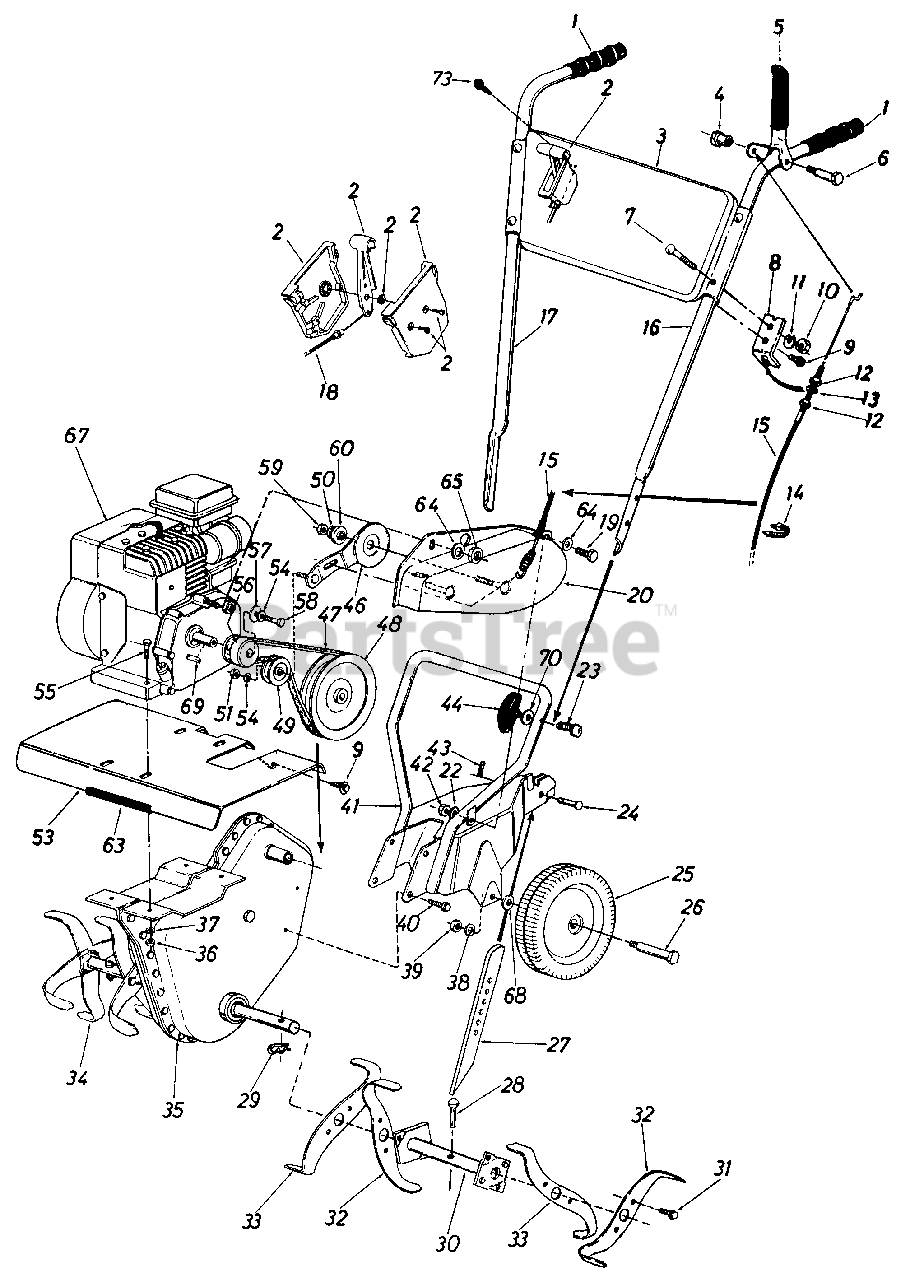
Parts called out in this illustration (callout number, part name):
2	CONTROL-THROTTLE
3	PANEL-HANDLE
4	NUT-SHLD
5	GRIP ASSY-CLUTCH-RH
6	SCREW-SHLD
7	BOLT-CARRIAGE 5/16-18 X 1.50
8	BRACKET-CLUTCH
9	SCREW-HEX WASH SF TAPP
10	NUT-HEX 5/16-18
11	WASHER-LOCK-5/16
12	NUT-HEX JAM 5/16-24
13	WASHER-LOCK-5/16
14	TIE-CABLE
15	CABLE-CLUTCH
19	SCREW-HEX 1/4-20 X .75
20	COVER-BELT
22	LOCK WASHER 1/4 DIA
23	BOLT-CARRIAGE 5/16-18 X 1.75
24	PIN-CLEVIS
25	WHEEL ASSY W/TIRE
26	SCREW-SHLD .498 DIA X 1.450 LG THD
27	BAR-DEPTH
28	PIN-CLEVIS
29	PIN-COTTER
34	TINE ASSY-COMP
35	CASE ASSY-CHAIN COMP
36	NUT-HEX 5/16-18
37	WASHER-LOCK-5/16
38	WASHER-HDL 3/8
39	NUT-HEX CENTER L-3/8-16
40	SCREW-HEX WASH SF TAPP
43	PIN-INTERN COT-5/16 DIA
44	KNOB-HANDLE ASSY
46	ARM-IDLER
47	BELT-V 3/8 X 29
49	PULLEY-IDLER-FLAT W/FLANGES
50	WASHER-LOCK-5/16
51	NUT-HEX INS L-3/8-24
55	SCREW-HEX 5/16-18 X 1.50
57	WASHER-FL-.385 X 1.00 X .135
58	BOLT-3/8 NF X 1"GR5
59	NUT-HEX 5/16-18
60	WASHER-BUSHING
63	STRIP-TRIM-12IN
64	WASHER-FL-.281 ID X .50 OD X .063
65	NUT-HEX CENTER L-1/4-20
68	WASHER-BELL .3/8ID X 1.12OD X .030
69	KEY-SQ 3/16 X .75
70	WASHER-BELL .337 X .867 X .057
73	SCREW-TRUSS TAP
